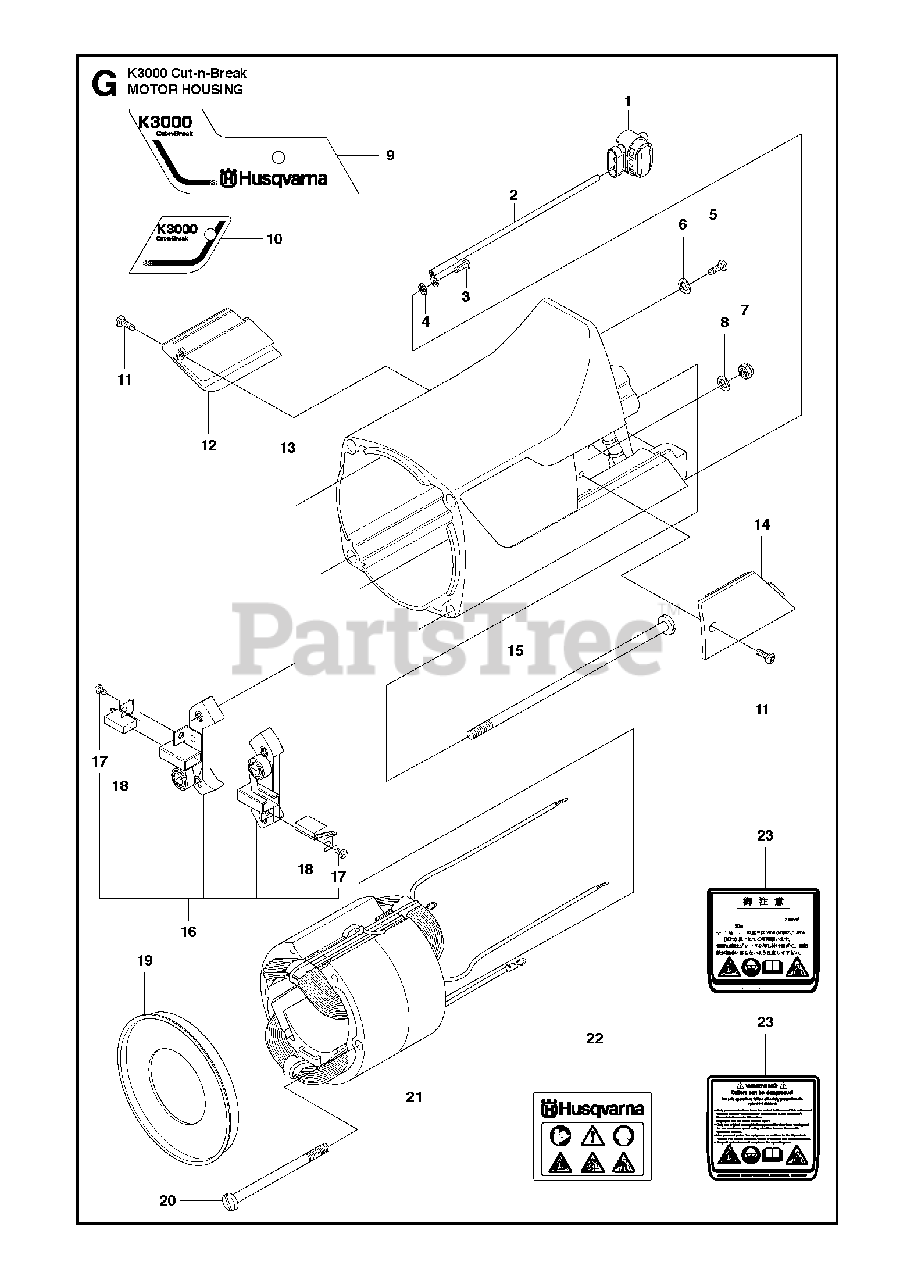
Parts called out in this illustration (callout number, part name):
1	COUPLER
3	SCREW CRPANM
6	SPRING WASHER
8	SPRING WASHER
11	SCREW CCRPANT
13	MOTOR HOUSING
16	BRUSH HOLDERIncl. 17, 18
17	SCREW SLPANM
18	CARBON BRUSH
19	AIR STREAM DIRECTOR
21	STATOR ASSY100 - 120V
21	STATOR ASSY230V
23	LABELUSA
